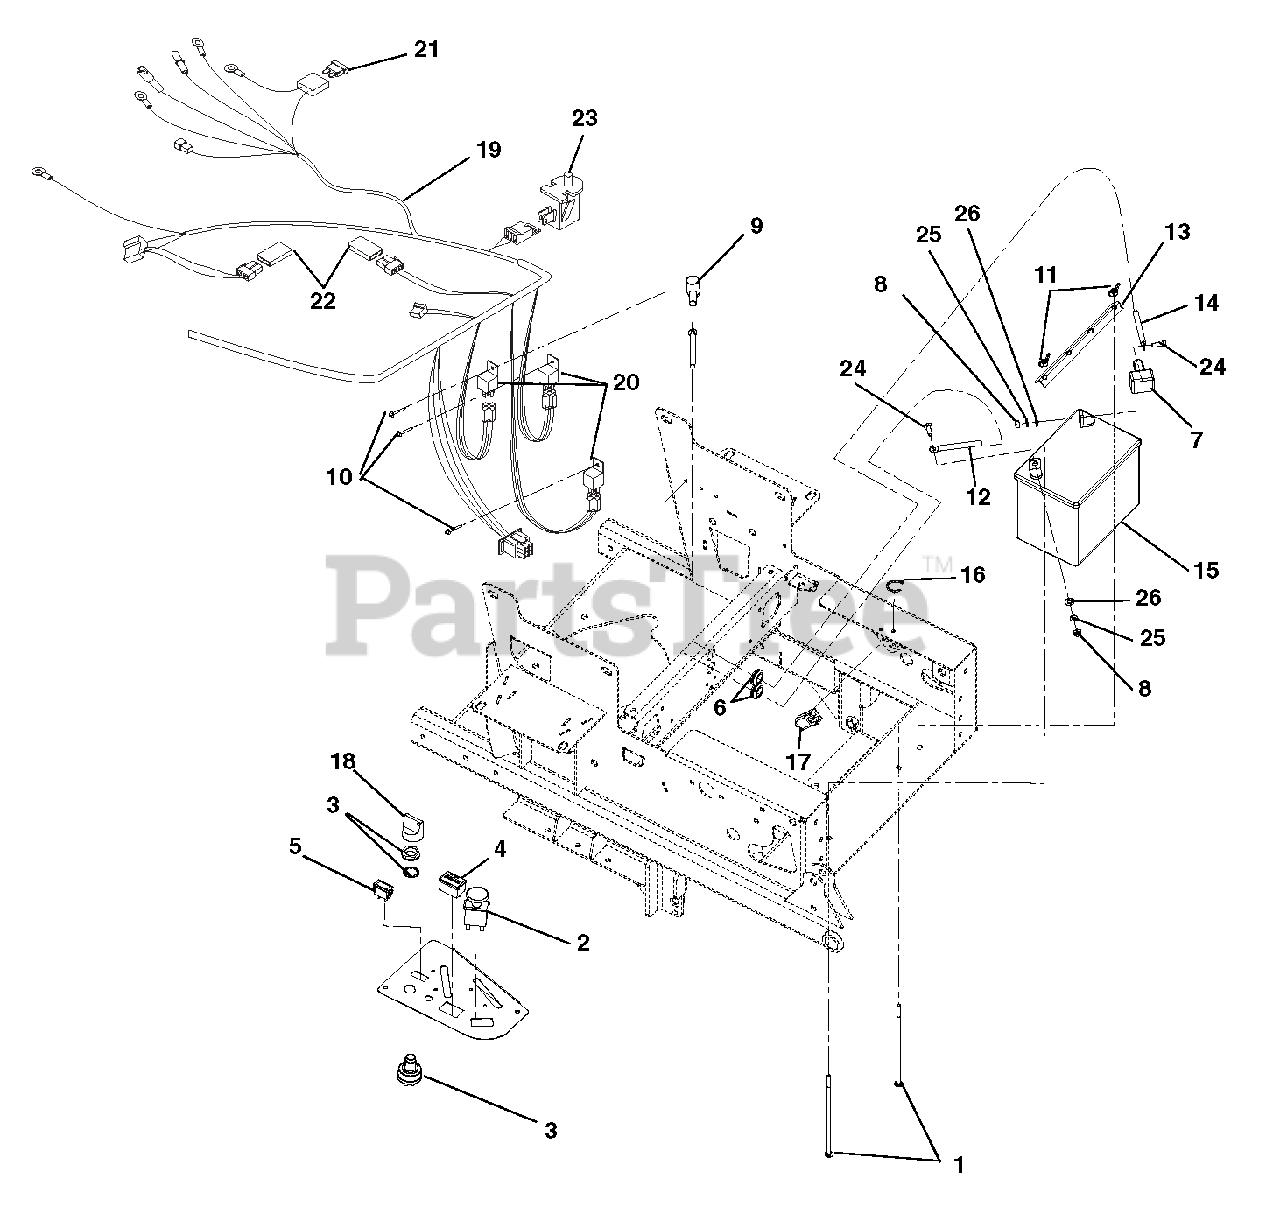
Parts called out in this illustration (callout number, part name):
1	BLT-RDHDSQNK .25-20X7.50 GR2YZ
2	SWITCH, CLUTCH
3	SWITCH, IGNITION
4	METER, HOUR W/MAINTENANCE
5	LIGHT,INDICATOR
6	GROMMET,RUBBER 5/8 ID/1.13 OD
7	INSULATOR
8	@NUT-HEX .25-20 YWZC
9	BOOT, BATTERY TERMINAL-RED
10	RIVET, .25 NYLON PANEL
11	NUT-LK WING .250-20 YWZC
12	CABLE, GROUND 22.00"
13	HOLD DOWN
14	CABLE-POSITIVE BATTERY 26.00"
15	BATTERY, 300 CCA 10U1L
16	CABLE TIE LG 5-1/2
17	SWITCH, SNAP IN - N.O./N.O.
18	KEY, W/ SHIELD
19	HARNESS - IZ, CZ, 100I
20	RELAY,SEALED W/DIODE
21	FUSE, 30 AMP.
22	DIODE, CONNECTOR SHELL
23	SWITCH- SNAP MTG N.O.
24	@BLT-HEX .25-20X.75 GR5 YWZC
25	@WSHR-LK .25X.062 REG YWZC
26	@WSHR-FL-STL.281X.62X.065 YWZC
